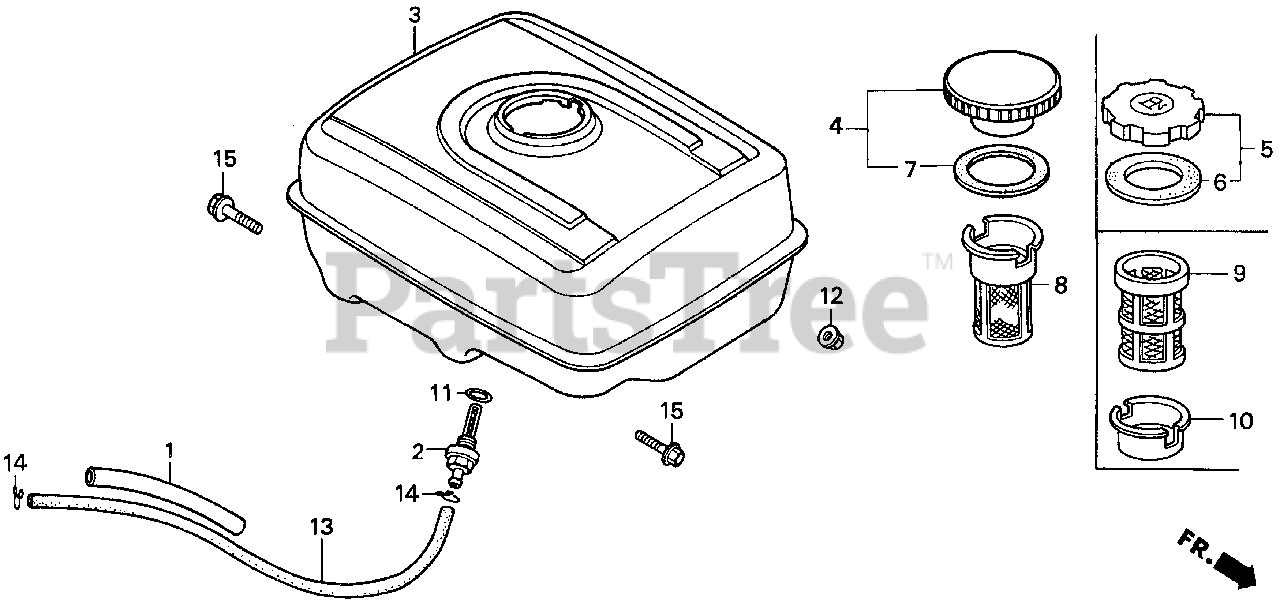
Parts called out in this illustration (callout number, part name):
1	RUBBER, SUPPORTER
1	RUBBER, SUPPORTER (107MM)
2	JOINT, FUEL TANK
3	TANK, FUEL *NH31* (MCKINLEY WHITE)
4	CAP, FUEL FILLER
5	CAP, FUEL FILLER
6	GASKET, FUEL FILLER CAP
7	GASKET, FUEL FILLER CAP
8	FILTER, FUEL
9	FILTER, FUEL
10	HOLDER, FUEL FILTER
11	O-RING (13.5X1.5) (ARAI)
12	NUT, FLANGE (8MM)
13	BULK HOSE, FUEL (4.5X3000) (4.5X235)
14	CLIP, TUBE (B8)
15	BOLT, FLANGE (8X25)
